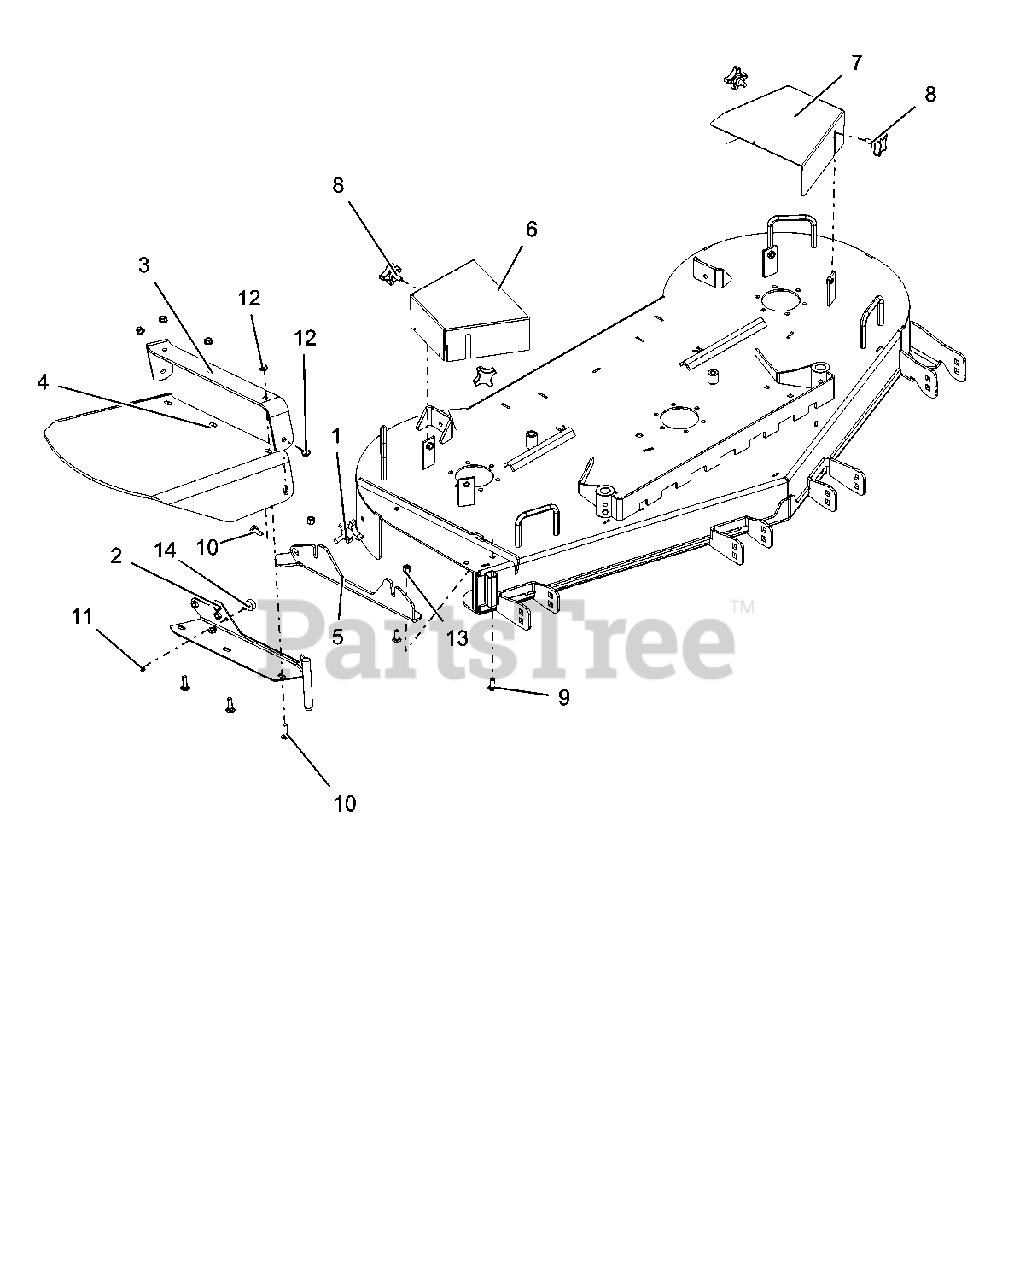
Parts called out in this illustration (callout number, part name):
1	KNOB, 3/8 X 1.25 - 4 PRONG
2	WLDT. DISCHARGE-RED
3	STRAP, WALK RUBBER DISCHARGE-RED
4	SHIELD, WALK RUBBER DISCHARGE
5	DISCHARGE, RUBBER BRKT-RED
6	PULLEY, SHIELD-RED
7	PULLEY, SHIELD LH-RED
8	KNOB, 3/8-16 x .75
9	BLT-RDHDSHSQNK.38-16X1.0 G5YZ
10	BLT-RDHDSQNK .38-16X1.25 G5 YWZC
11	@NUT-SPNLK-FLG .25-20 YWZC
12	@NUT-SPNLK-FLG .375-16 YWZC
13	NUT-LK-NYL .38-16 YWZC
14	BUMPER, RUBBER
